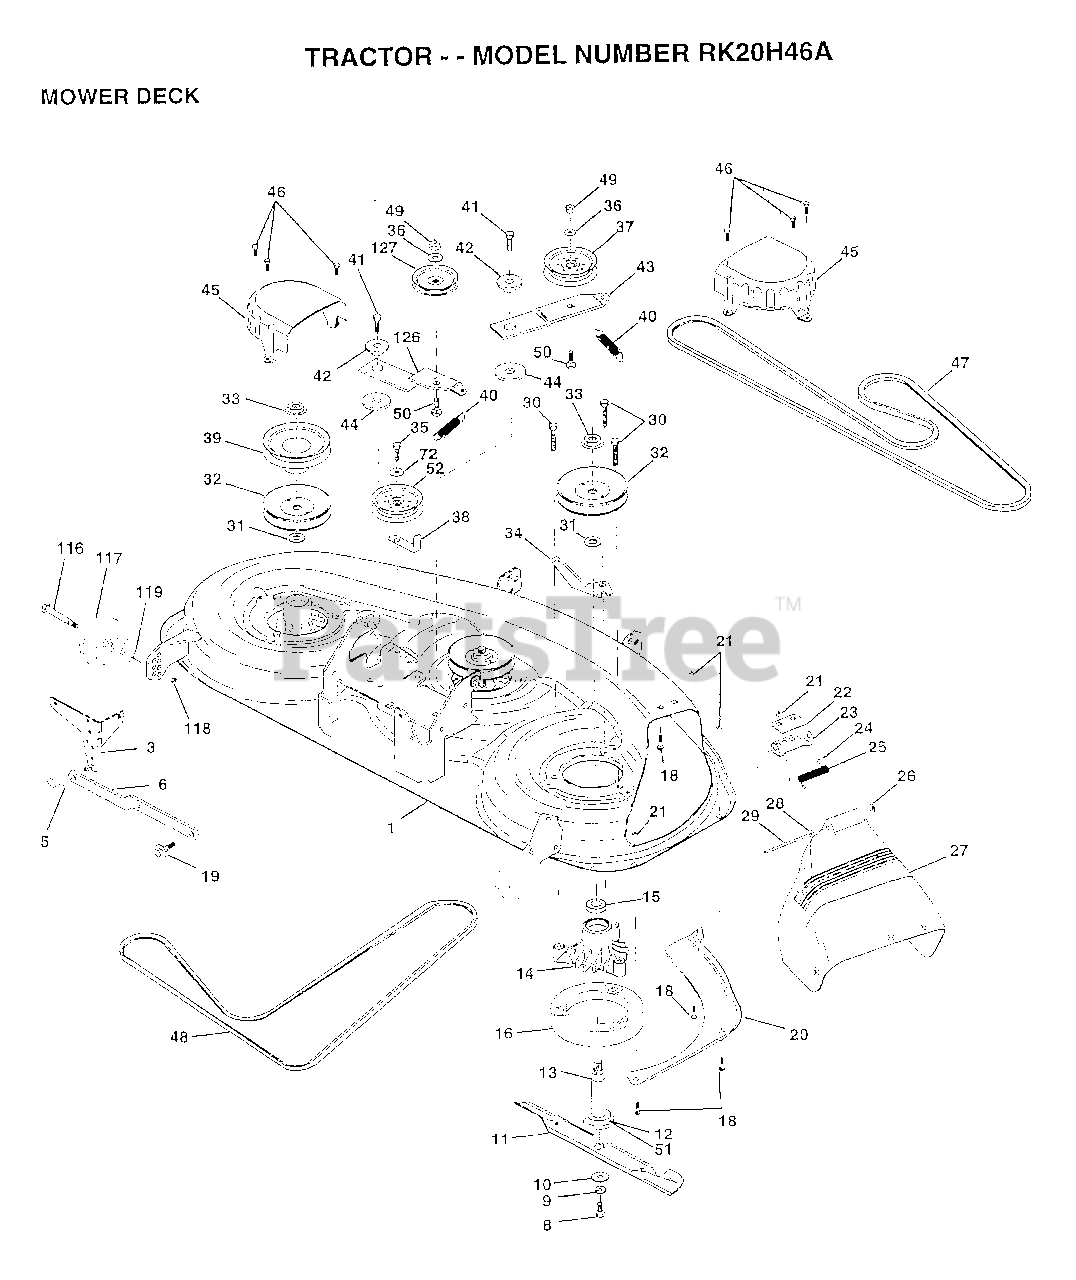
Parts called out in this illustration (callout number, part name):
1	DECK.WELDMENT.MOWER
3	BRKT.ASM.SW.44/50
8	BLADE BOLT
10	WASHER.HARD.BLADE
11	"BLADE MULCH 46"""
11	"BLADE.HIGHLIFT46"""
11	BLADE.HI LIFT PRE
12	BEARING.BALL
13	SHAFT.ASM.W/BRNG
14	HOUSING.MAND.44.V
15	BEARING
16	STRIPPER RND MWR
18	BOLT
19	BOLT SHD 5/16-18
20	BAFFFLE.VORTEX.46
22	STIFFENER BRKT
23	DEFLECTOR BRKT
24	CAP-SLEEVE LT
26	NUT PUSH M
27	SHIELD DEFLECTOR
28	WASHER
29	HINGE ROD
30	"SCREW-THD ROLL,WA"
31	WASHER
32	PULLEY.MAND.36/46
34	ANCHOR.SPRING.46
35	SCREW LT
36	WASHER
37	FLAT IDLER PULLEY
38	"KEEPER BELT,IDLER"
39	PULLEY.DRV.DCK.46
40	"SPRING.SEC.44""VEN"
41	SCREW
42	SPACER RETAINER
43	ARM.IDLER.DECK.46
44	HARDENED WASHER
45	COVER.MANDREL.46
46	SCREW.1/4-20X5/8
47	BELT-V.SEC.46.KEL
48	BELT.MWR.PRM.85.4
50	BOLT.3/8-16X1.50
51	WASHER.FELT.
52	"PULLEY IDLER,FLAT"
72	WASHER HYT
116	BOLT.SHOULDER
117	WHEEL GAGE DONUT
118	LOCKNUT
119	WASHER
126	ARM.IDLER.PRIM.46
127	PULLEY.IDLER.4.25
